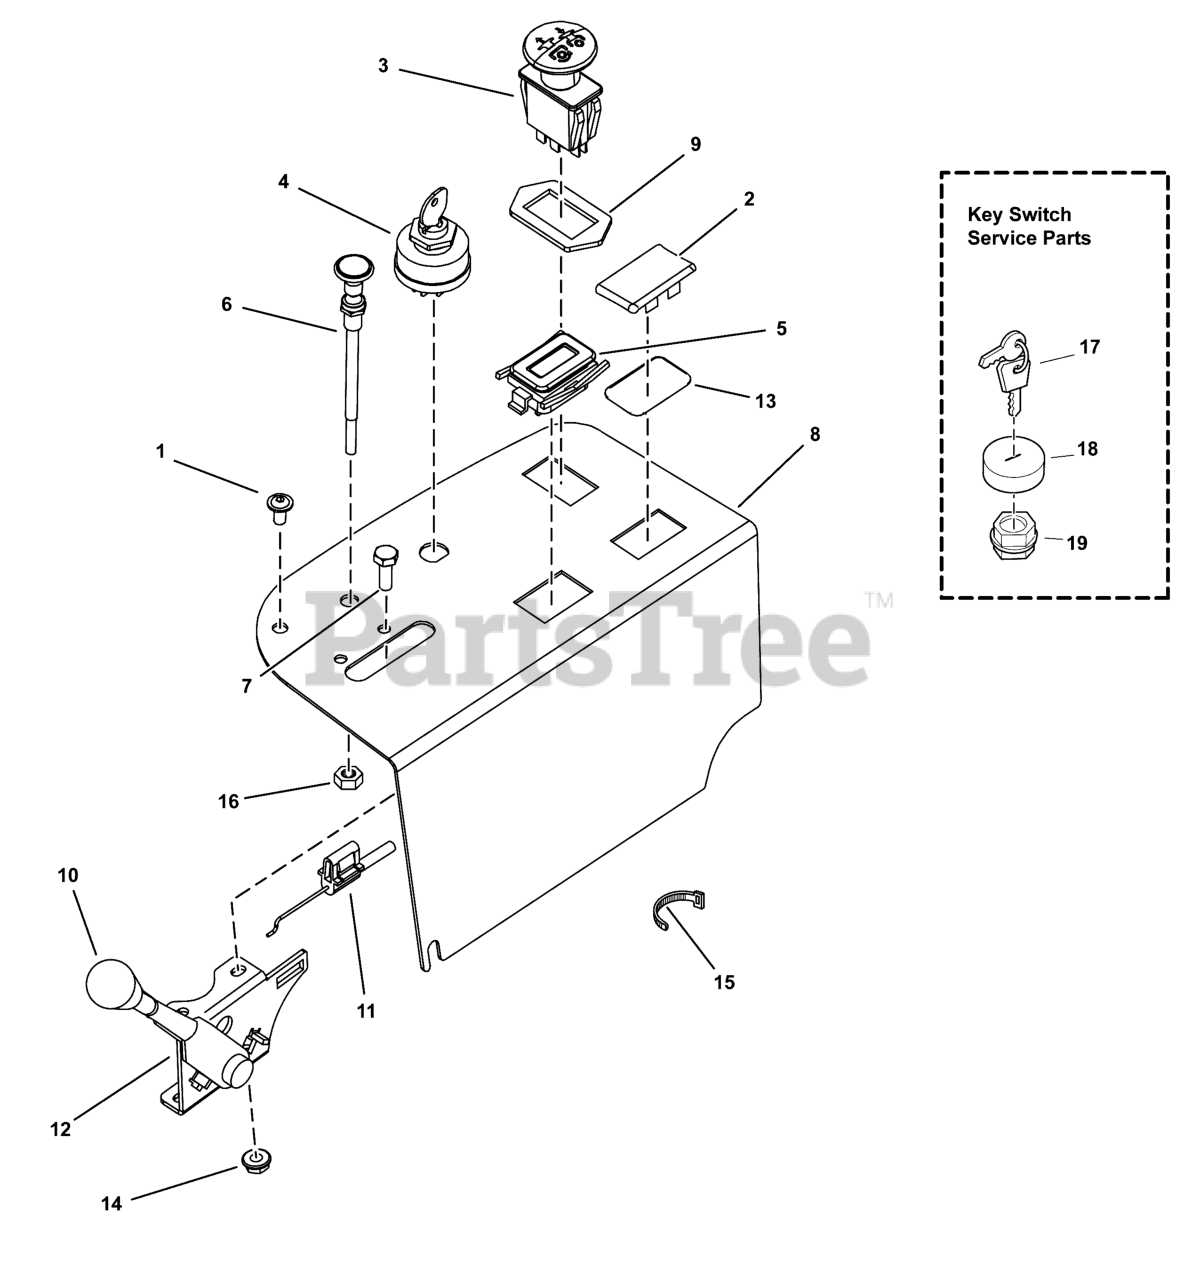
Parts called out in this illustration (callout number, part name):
1	SCREW, FLANGE, ALLEN HD, 1/4-20X.5 S/S
2	PLUG, .820X1.44 HOLE, BLACK PLASTIC
3	SWITCH-PTO PUSH
4	SWITCH, IGNITION, 6 POST
5	HOURMETER
6	CABLE, CHOKE CONTROL, 51" (Z)
7	SCREW, #10-24 X 3/4" ROUND PHILLIPS
8	PANEL, CONTROL, IS2100Z - BLK
9	RING, SWITCH RETAINER
10	THROTTLE CONTROL HANDLE/KNOB
11	CABLE, THROTTLE, 52"
12	LEVER, THROTTLE CONTROL, HEAVY-DUTY
13	O-RING, 7/8" ID X 1/16" W
14	NUT, Hex, Nylon Lock, #10-24
15	TIE, SELF-LOCKING, 12"
16	NUT, 3/8-24 HEX (SV)
17	KEY, IGNITION MOLDED SET
18	COVER, PLASTIC, SNAP ON
19	PLASTIC NUT
